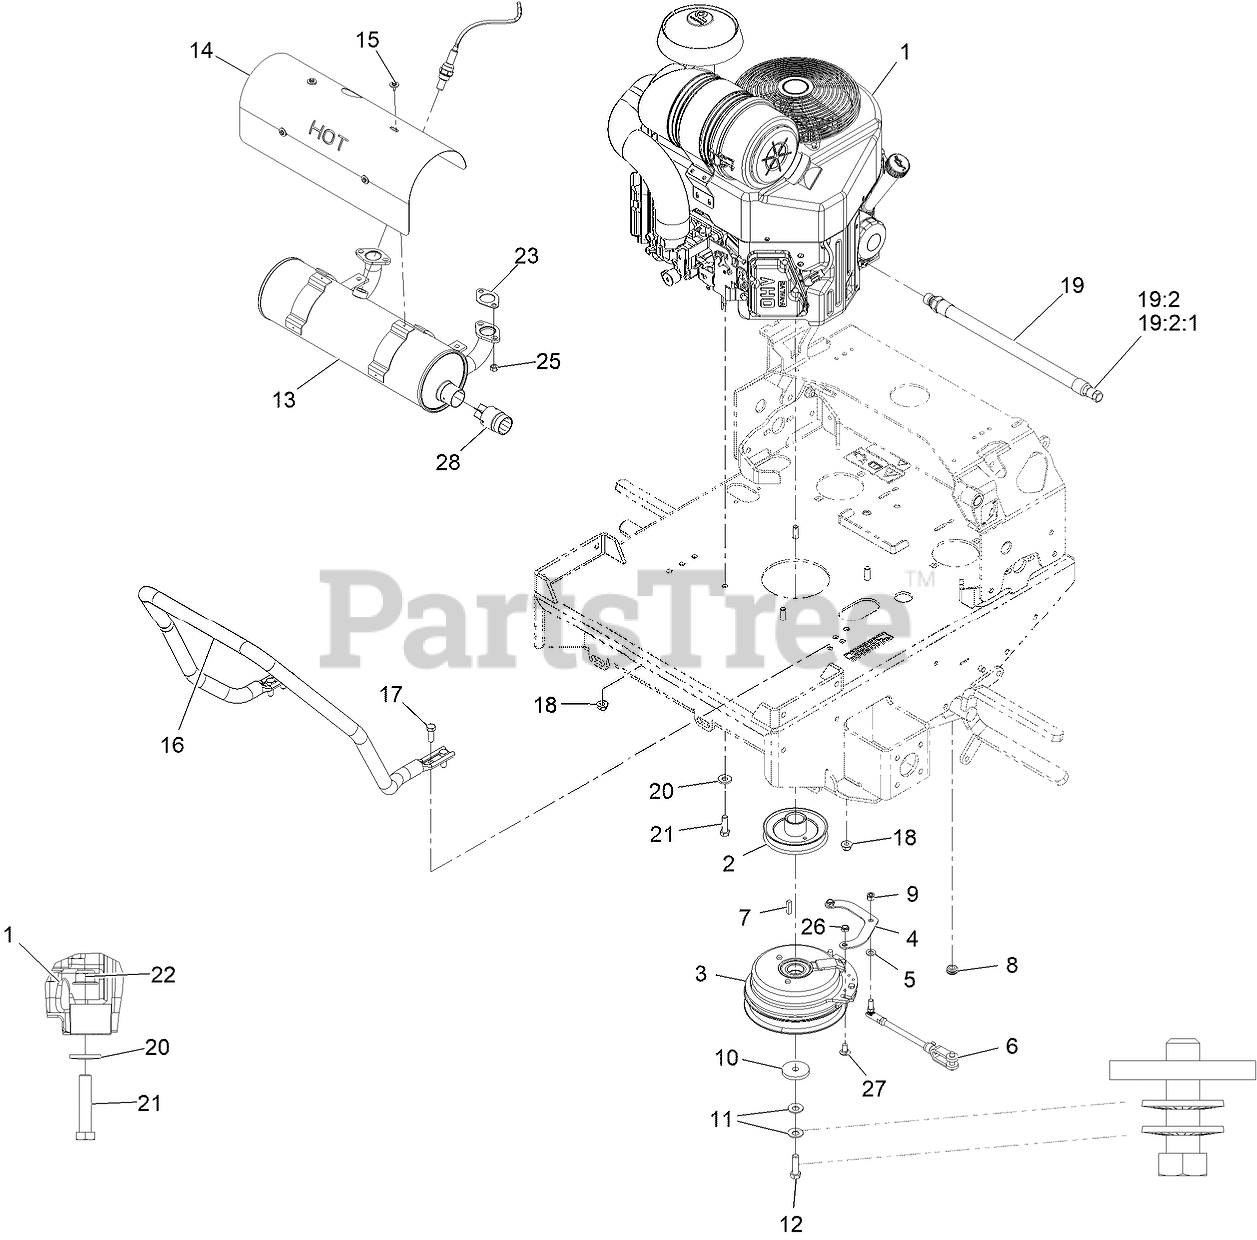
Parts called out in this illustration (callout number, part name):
2	SHEAVE W/ HUB
3	CLUTCH, 200 FT/LBS, 1.13
4	STRAP, CLUTCH
5	WASHER-PLAIN
6	ASM, CLUTCH ANCHOR
7	KEY
8	GROMMET
9	NUT-LOCK
10	WASHER-CLUTCH
11	WASHER-SPRING
12	BOLT-HEX, TAP
13	MUFFLER-TTX, EFI
14	SHIELD-MUFFLER,TTX EFI
15	SCREW-HH, THREAD FORMING
16	TUBE-GUARD AIR CLEANER
17	SCREW-HH
18	NUT-HF, NI
19	OIL DRAIN HOSE ASM
19:2	PLUG-HH
19:2:1	O-RING
20	WASHER-SPRING
21	SCREW-HH
22	NUT-HF, NI
23	GASKET-EXHAUST
25	NUT-FLANGE
26	NUT-LOCK, NI
27	SCREW-CARR
28	Screen-Spark Arrestor
